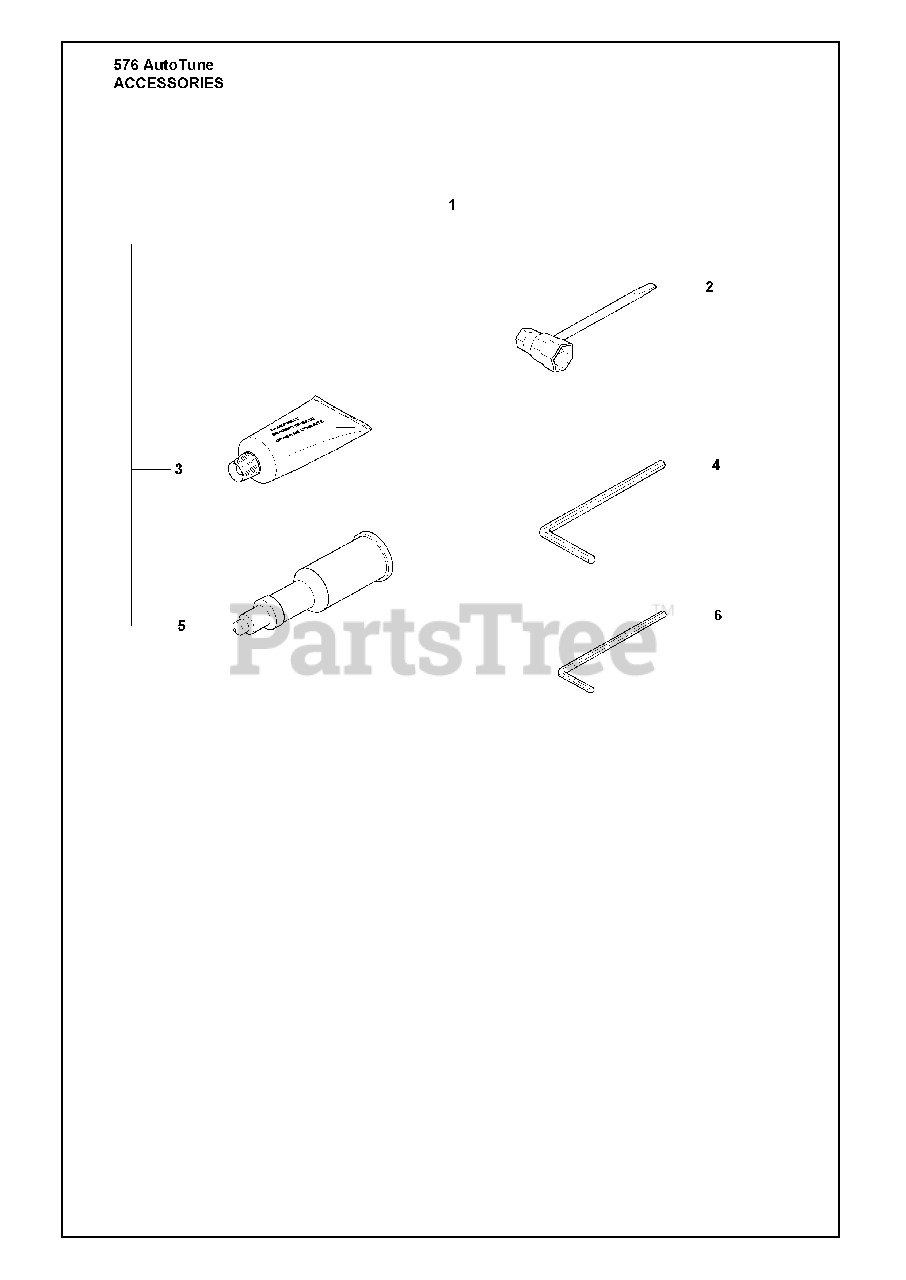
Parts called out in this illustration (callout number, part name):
1	TOOL KIT
2	COMBI TOOL
3	GREASE
5	Grease Gun
